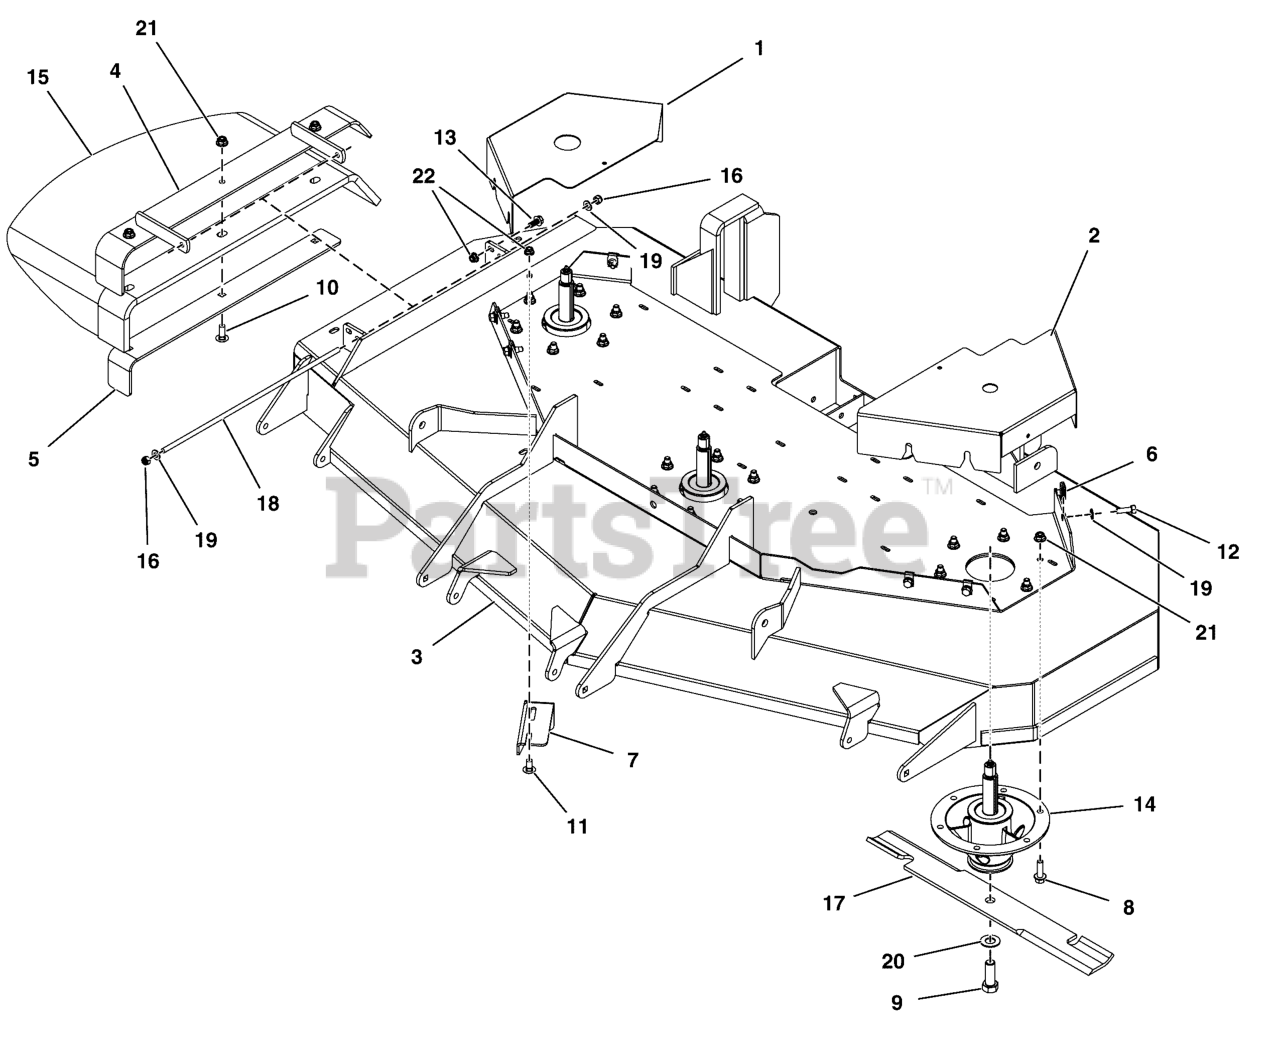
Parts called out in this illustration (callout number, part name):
1	GUARD, RH 61 DECK, SRSZ2 - RED
1	GUARD, RH, 61" - RED
2	GUARD, LH 61 DECK, SRSZ2 - RED
2	GUARD, LH, 61" - RED
3	DECK SHELL W/DECALS 61 SRSZ2 5414261B
3	DECK SHELL W/DECALS, 61, SRSZ2 (5422062B)
5	SUPPORT, DISCHARGE CHUTE - BLK
6	BODY CLIP, 5/16-18-7GA MATERIAL
7	PLATE, DEFLECTOR - BLK
8	BOLT, 3/8-16 X 1-1/2, FLANGE, GD 5, CZ
9	BOLT, 5/8-11 X 1-3/4 GD8
10	BOLT, 3/8-16 X 1-1/2, CARRIAGE, GD5, CZ
11	BOLT, 5/16-18 X 3/4, CARRIAGE, GD5, CZ
12	BOLT, 5/16-18 X 1" GRD5 YZ
13	BOLT, 5/16-18 X 3/4 GD5
14	SPINDLE ASSM, CAST IRON 8.0-6 BOLT, LS
15	CHUTE, RUBBER DISCHARGE (5104442)
16	NUT, 5/16-24 HEX NYLON LOCK
17	BLADE SET, 61 DECK (3)
18	ROD, MOUNT, CHUTE, 61, CZ
19	WASHER, 5/16" SAE
20	WASHER, BLADE BOLT, 9/16" F436, CZ
21	NUT, 3/8 - 16 HEX NYLOCK FLANGE
22	NUT, 5/16-18 HEX NYLOCK FLANGE NUT
